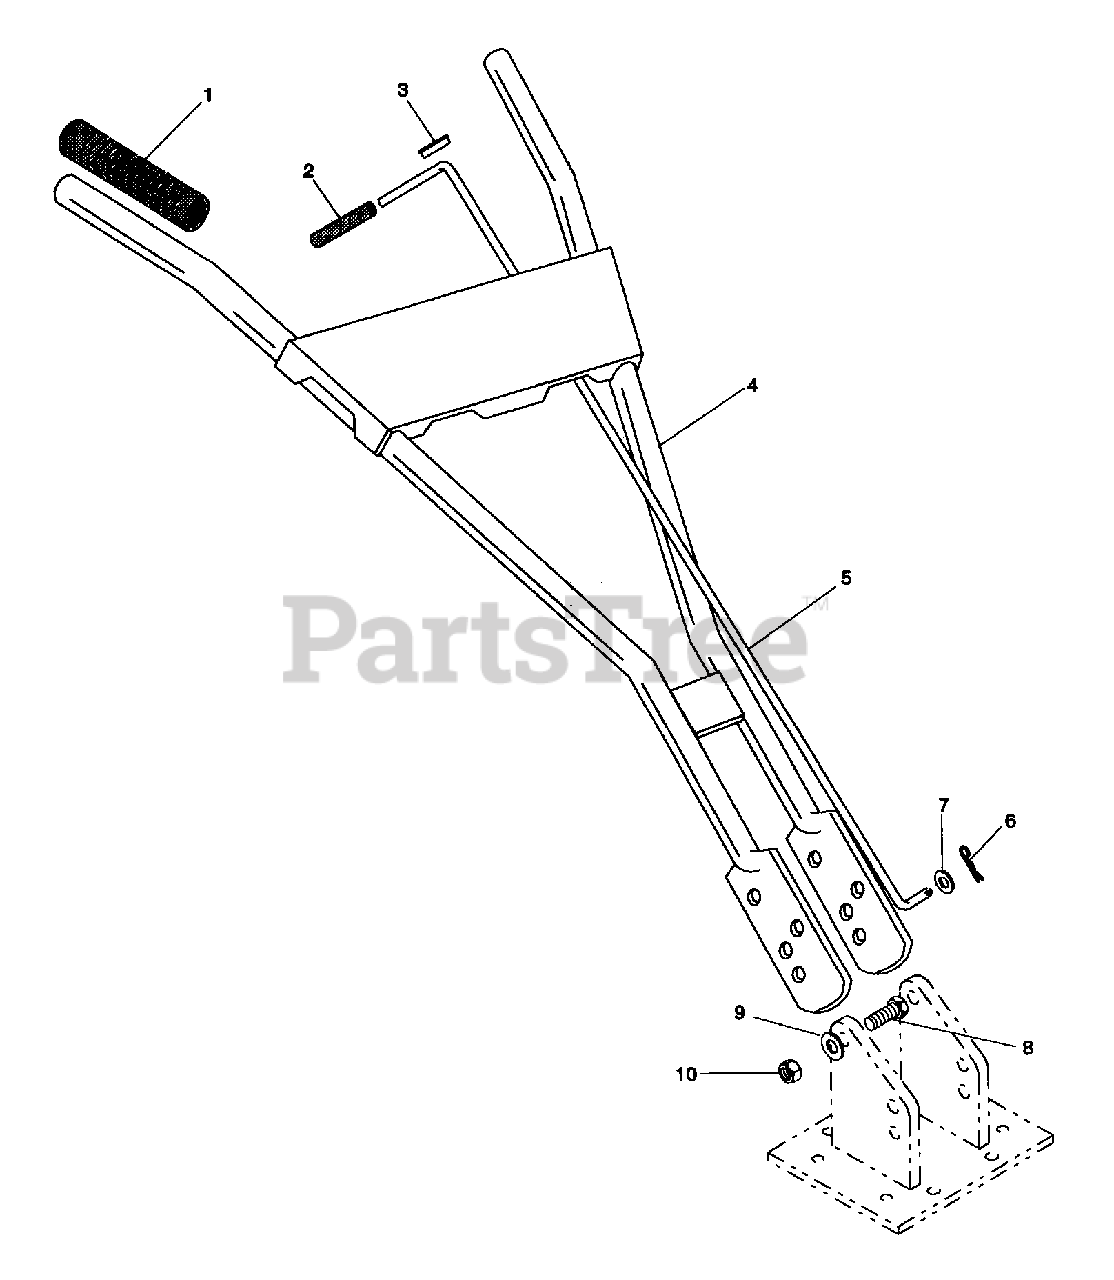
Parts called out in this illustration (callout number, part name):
1	HANDLEGRIP
2	GRIP - 5/16 ID X 2 7/8 - BLACK
3	SNAP BUSHING
4	HANDLEBAR RT 5018
5	SHIFT LEVER ROD
6	PIN-HAIR INT.06X.25X1.12
7	WSHR-FL-STL.344X.688X.065PL
8	BLT-HEX .38-16X1.00 PL
9	WSHR-FL-STL.406X.812X.065PL
10	NUT-LK-CTR .375-16 GR A PL
